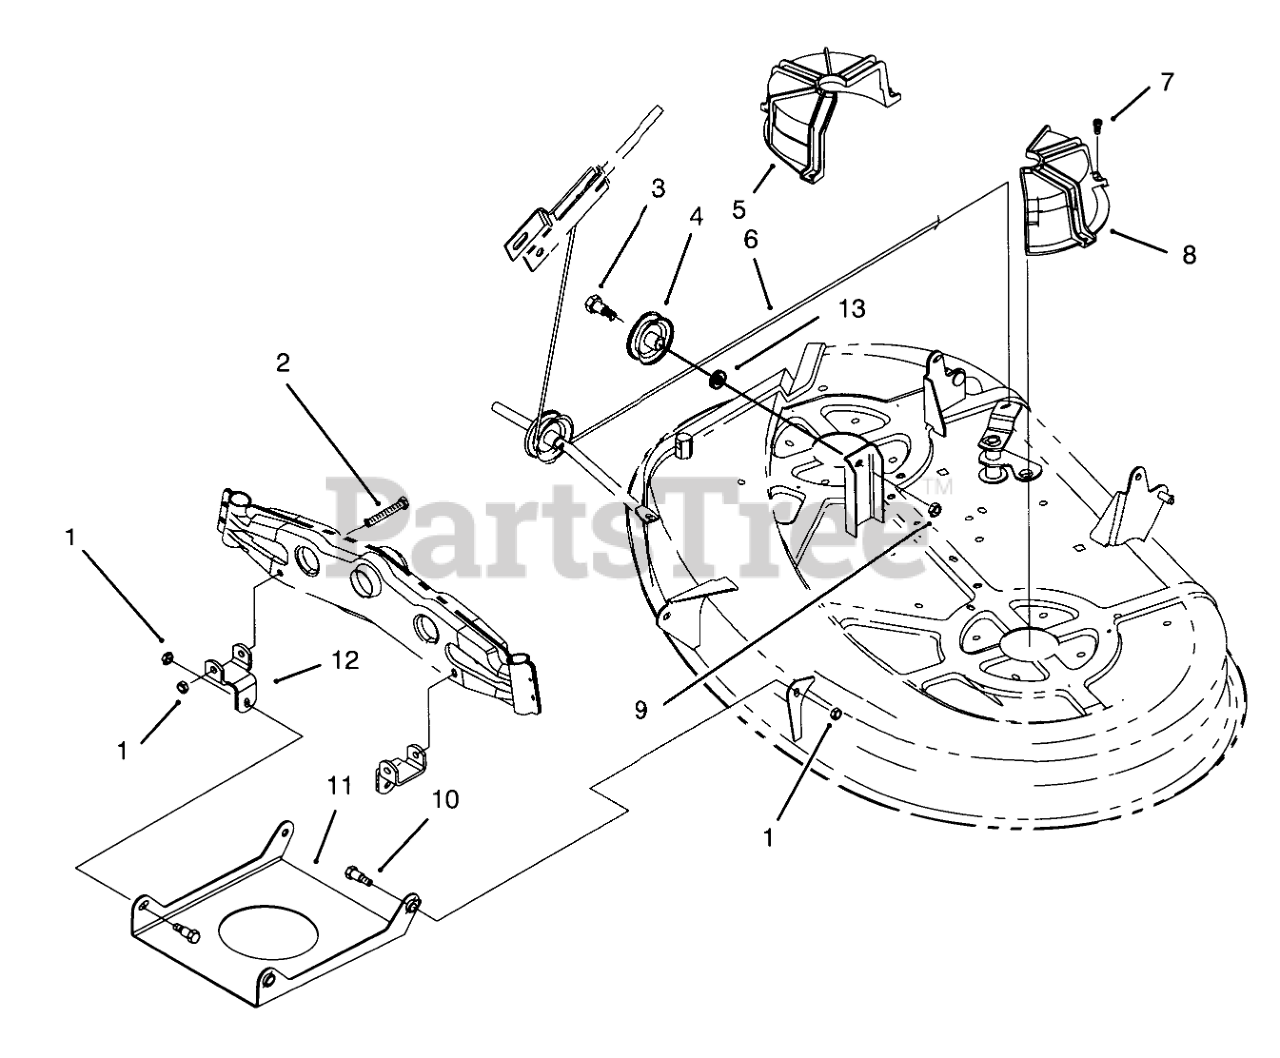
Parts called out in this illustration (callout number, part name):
1	NUT-LOCK, NI
2	SCREW-HH
3	SCREW-SHOULDER, HH
4	PULLEY, CABLE
5	GUIDE-BELT, RH
6	DECK ENGAGE CABLE
7	SCREW-HWHTF
8	GUIDE-BELT, LH
9	NUT-LOCK, NI
10	BOLT-SHOULDER
11	Pan-Front Deck Suspension
12	Bracket-Deck Suspension
13	WASHER-FLAT
